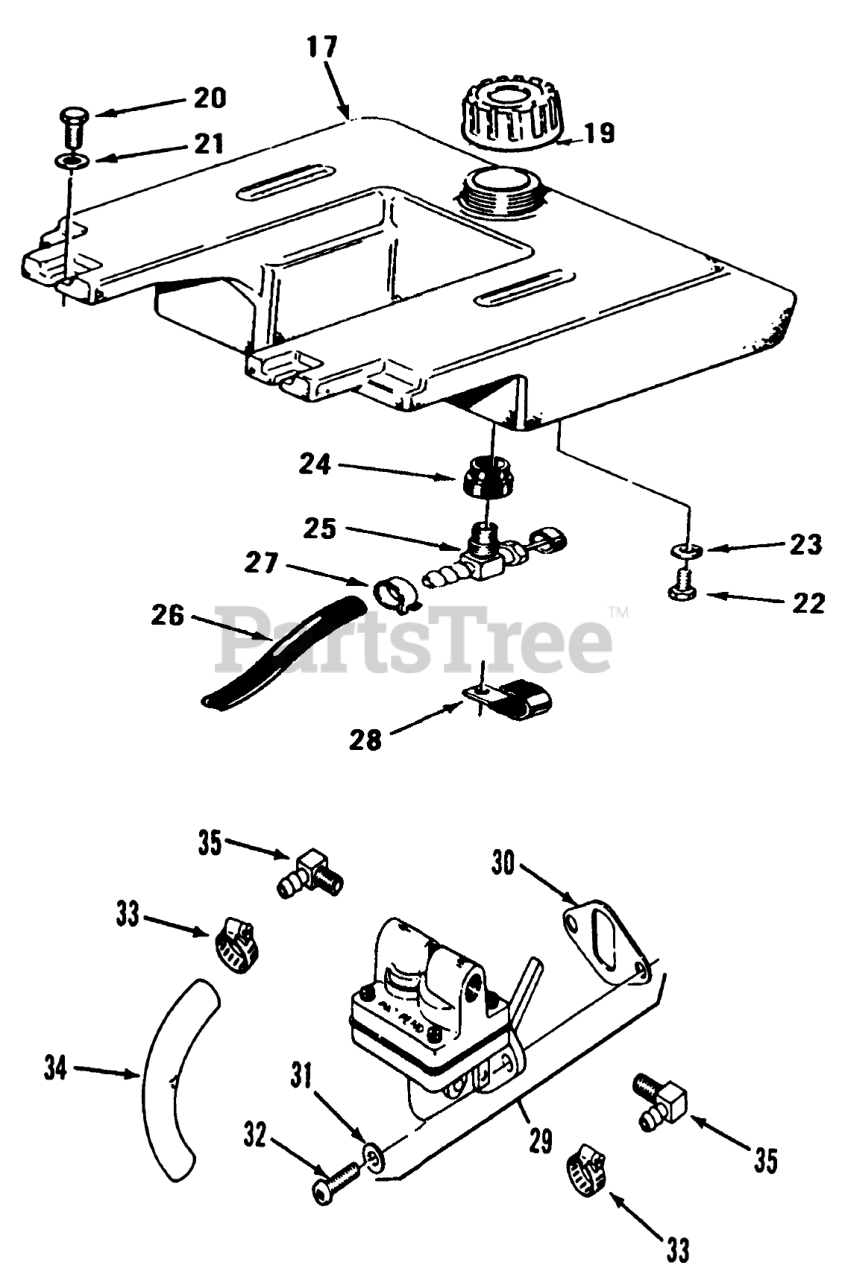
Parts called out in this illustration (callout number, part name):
17	TANK-FUEL
18	GAS CAP ASM
20	Bolt
21	WASHER-FLAT
22	SCREW-HH
23	WASHER-LOCK
24	BUSHING
25	VALVE-FUEL
26	Fuel Line 62
27	Clamp
28	Clamp
29	Pump Assy-Fuel (Includes Items 30 & 31)
30	Gasket
31	Washer
32	Screw-Pozidrive
33	Clamp
34	Line-Fuel
35	Connector 90
